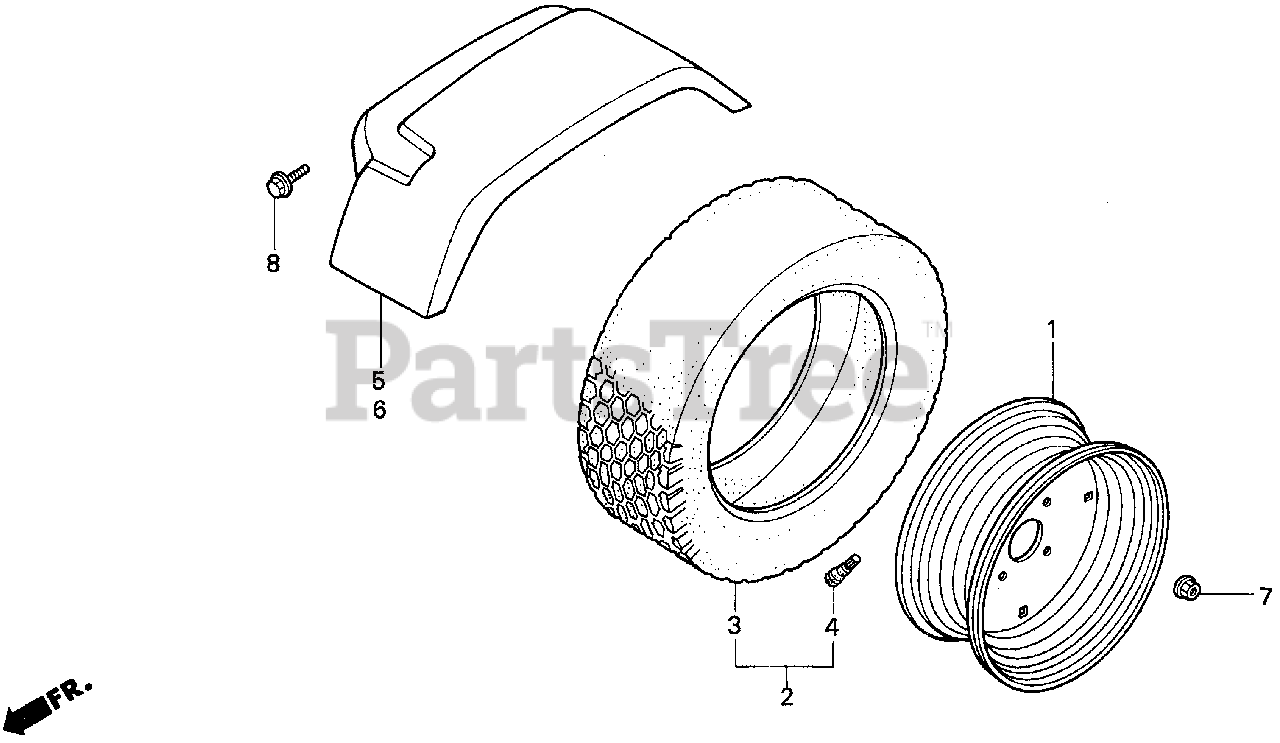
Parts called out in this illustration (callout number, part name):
1	WHEEL (12X5JA) (WDC)
1	WHEEL (14X6JJ)
2	TIRE ASSY., RR. (24X8.00-14) (2PR) (OHTSU)
3	TIRE, RR. TUBELESS (7-12-4PR)
4	VALVE, RIM
5	FENDER, R. RR. *R165* (JOLLY RED)
5	FENDER, R. RR. *R280* (POWER RED)
6	FENDER, L. RR. *R280* (POWER RED)
7	NUT, WHEEL (12MM)
8	BOLT, FLANGE (8X16)
